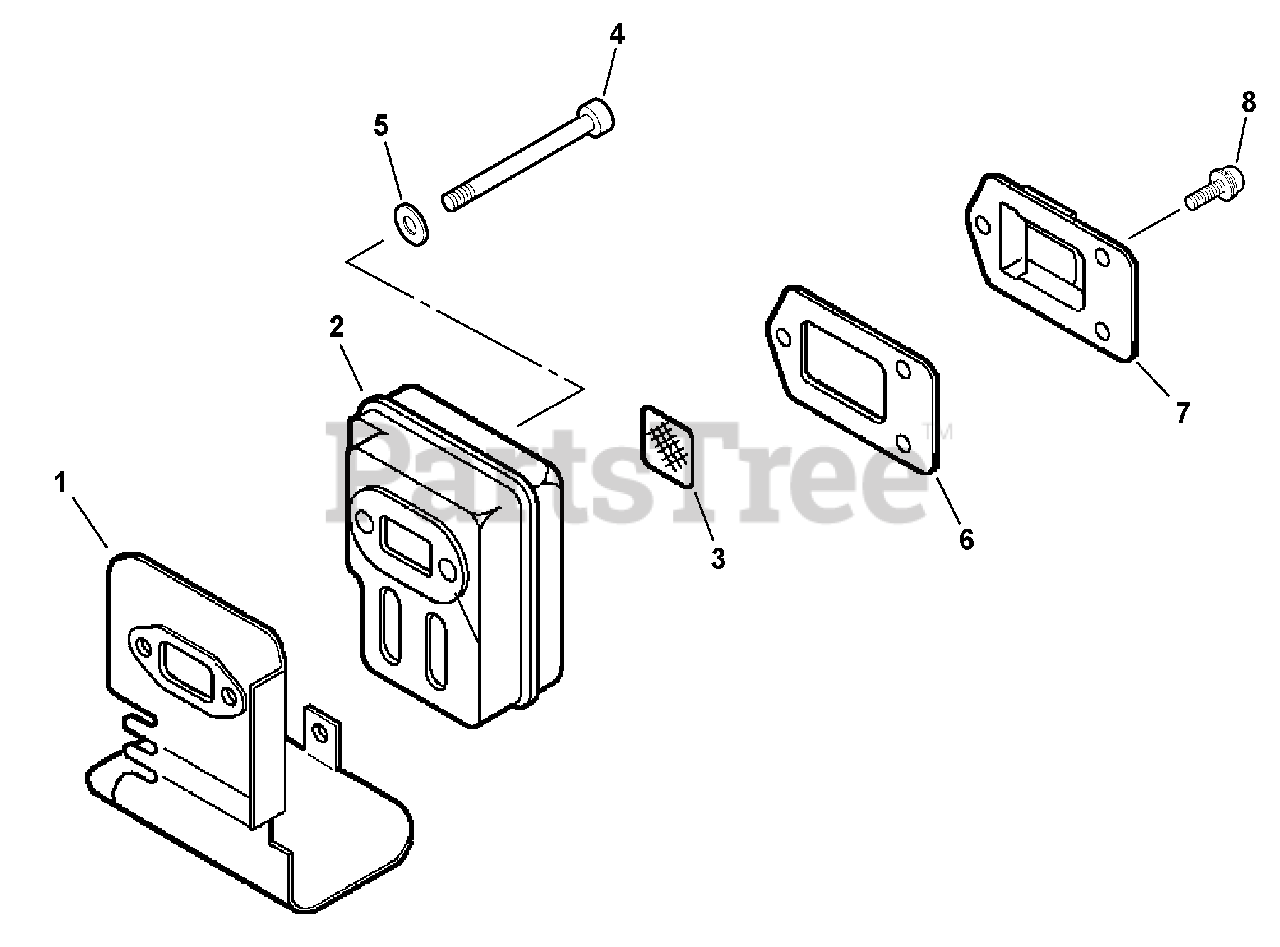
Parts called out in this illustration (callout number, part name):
1	HEAT SHIELD, EXHAUST
3	SCREEN, SPARK ARRESTER
4	BOLT 5×55
5	WASHER, FLAT 5.5×10×0.8
6	GASKET, EXHAUST
7	GUIDE, EXHAUST
8	SCREW 4×10
